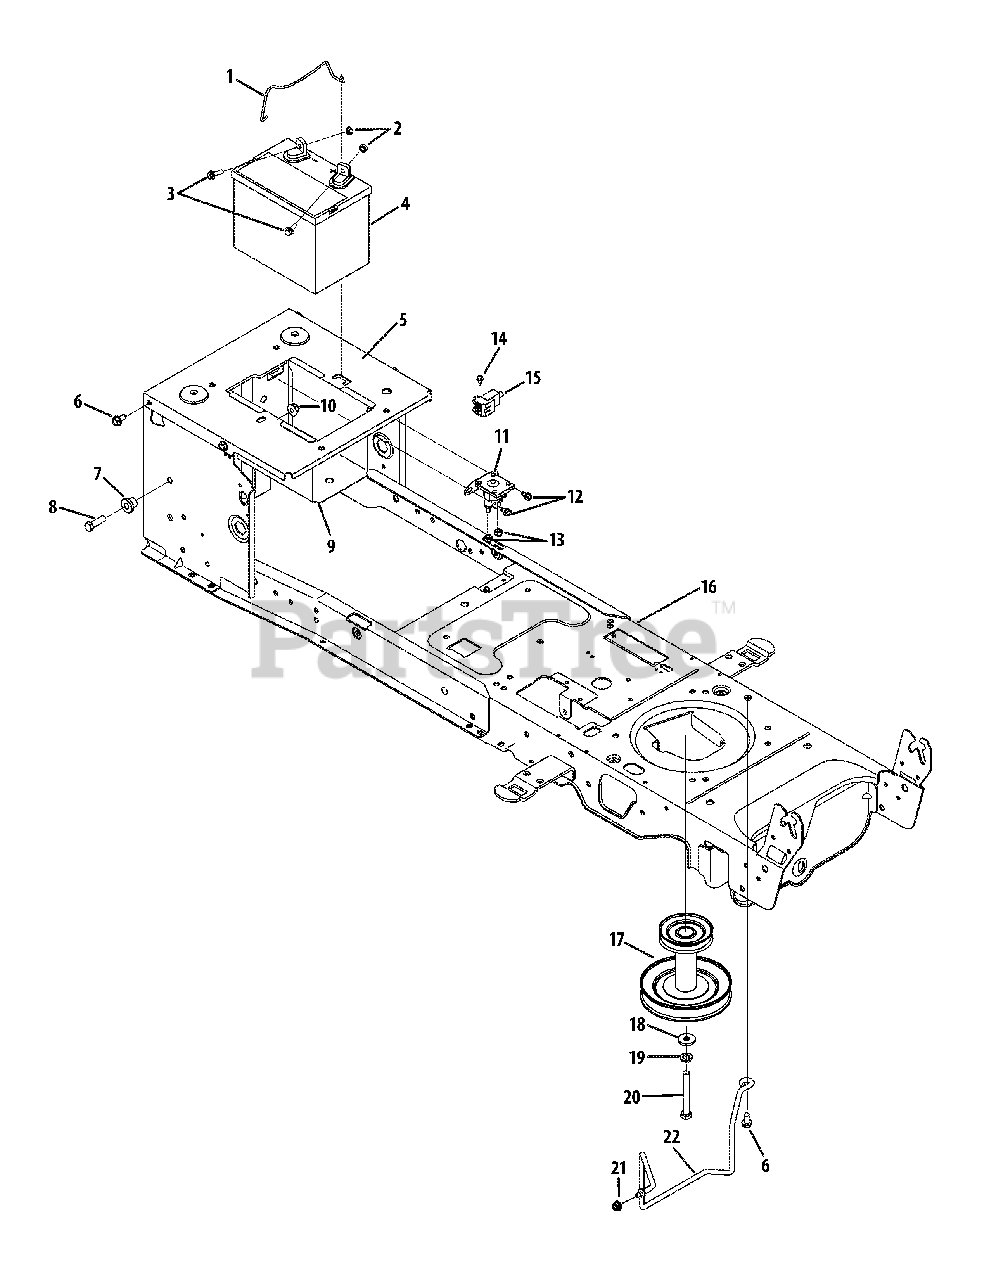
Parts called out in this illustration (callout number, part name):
1	Battery Hold-Down Rod
2	Sems Nut, 1.4-20
3	Hex Flange, 1.4-20 x .75
5	Seat Frame Bracket
6	Hex Washer Screw, 5.16-18 x .750
7	Shoulder Spacer, .38 x 1.0 x .70
8	Hex Screw, 3.8-16 x 1.25
10	Flange Lock Nut, 3.8-16
11	Solenoid
12	Hex Washer Screw, 1.4-20 x .375
13	Flange Lock Nut, 1.4-20
14	Shoulder Screw, #10-32 x .500
15	Interlock Switch
16	Lower Frame Assembly
17	Engine Pulley
18	Flat Washer, .450 x 1.250 x .164
19	Lock Washer, 7.16
20	Hex Screw, 7.16-20 x 2.75
21	Flange Lock Nut, 5.16-18
22	Keeper Rod
